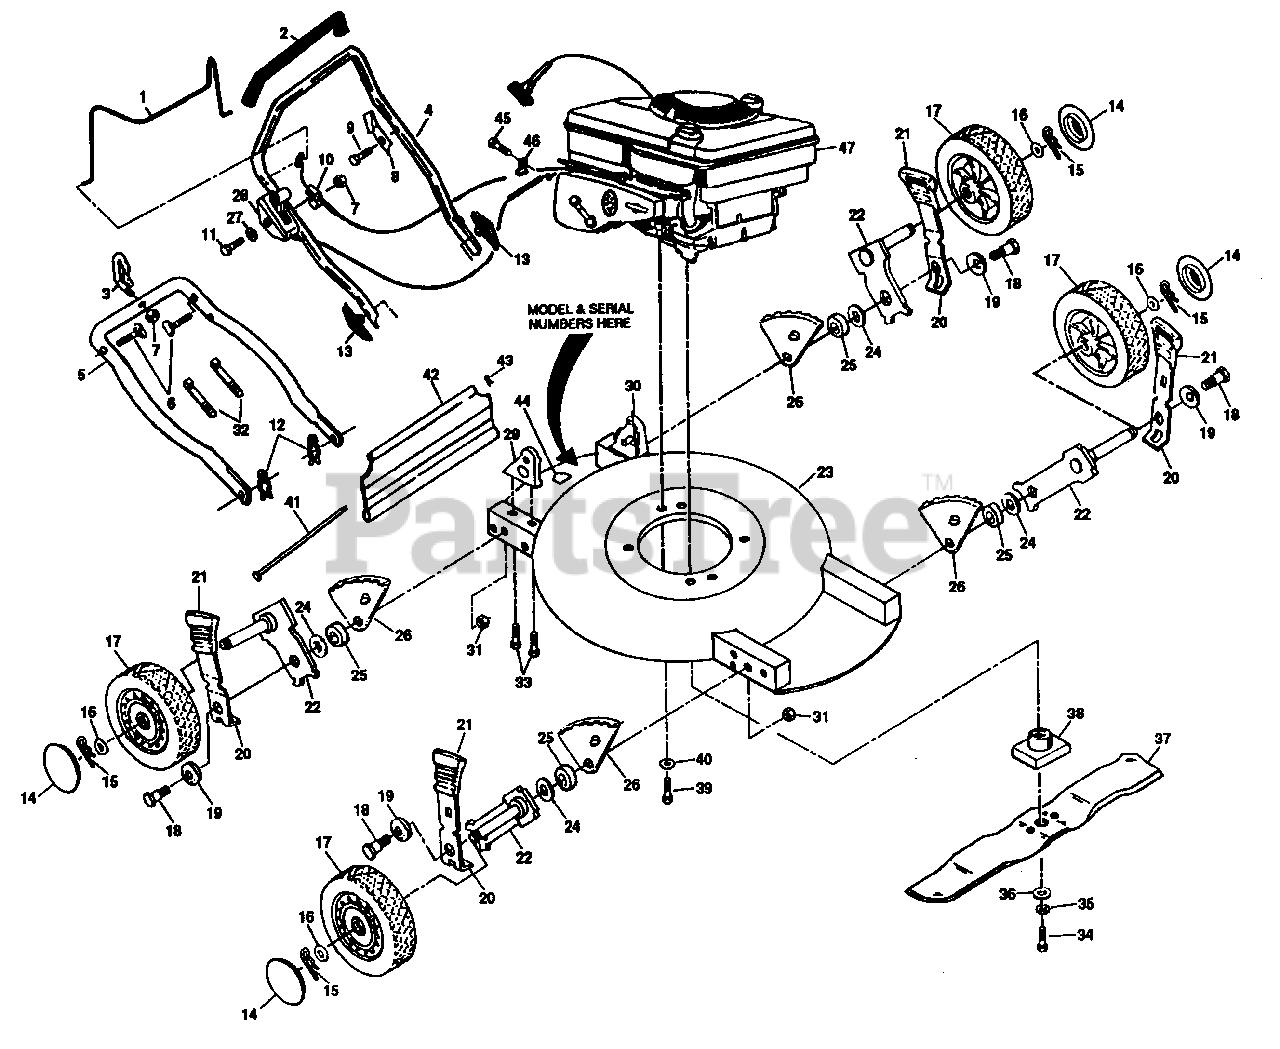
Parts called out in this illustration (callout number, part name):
1	Control Bar
2	Handle Grip (AYP part number)
3	Rope Guide (AYP part number)
4	Upper Handle (AYP part number)
5	Lower Handle (AYP part number)
6	Handle Bolt 5/16-18 x 1-3/4
7	Locknut 1/4-20 (AYP part number)
8	Up-Stop Bracket (AYP part number)
9	Hex Washer Head Screw #10-24 x 1/2 (AYP part number)
10	Engine Zone Control Cable (AYP part number)
11	Pan Head Screw 1/4-20 x 2-1/8 (AYP part number)
12	Hairpin Cotter (AYP part number)
13	Handle Knob (AYP part number)
15	Retainer Clip (AYP part number)
16	Washer (AYP part number)
17	Wheel & Tire Assembly 8.0 x 1.75 (AYP part number)
18	Shoulder Bolt (AYP part number)
19	Belleville Washer (AYP part number)
20	Selector Spring (AYP part number)
21	Selector Knob (AYP part number)
22	Axle Arm Assembly (AYP part number)
23	Lawn Mower Housing
24	Washer (AYP part number)
25	Spacer (AYP part number)
26	Wheel Adjusting Bracket (AYP part number)
27	Washer (AYP part number)
28	Throttle Control
29	Handle Bracket Assembly (Right) (AYP part number)
30	Handle Bracket Assembly (Left) (AYP part number)
31	Locknut 3/8-16 (AYP part number)
32	Wire Tie (AYP part number)
33	Thread Cutting Screw 5/16-18 x 3/4 (AYP part number)
34	Hex Head Screw 3/8-24 x 1-3/8
35	Helical Lockwasher 3/8 (AYP part number)
36	Hardened Washer (AYP part number)
37	20" Blade
38	Blade Adapter (AYP part number)
39	Hex Head Thread Rolling Screw 3/8-16 x 1-1/8 (AYP part number)
40	Washer (AYP part number)
41	Skirt Rod (AYP part number)
42	Rear Skirt (AYP part number)
43	Retainer Clip (AYP part number)
44	Danger Decal (AYP part number)
45	Thread Rolling Screw #10-32 x 5/8 (AYP part number)
46	Cable Clamp (AYP part number)
